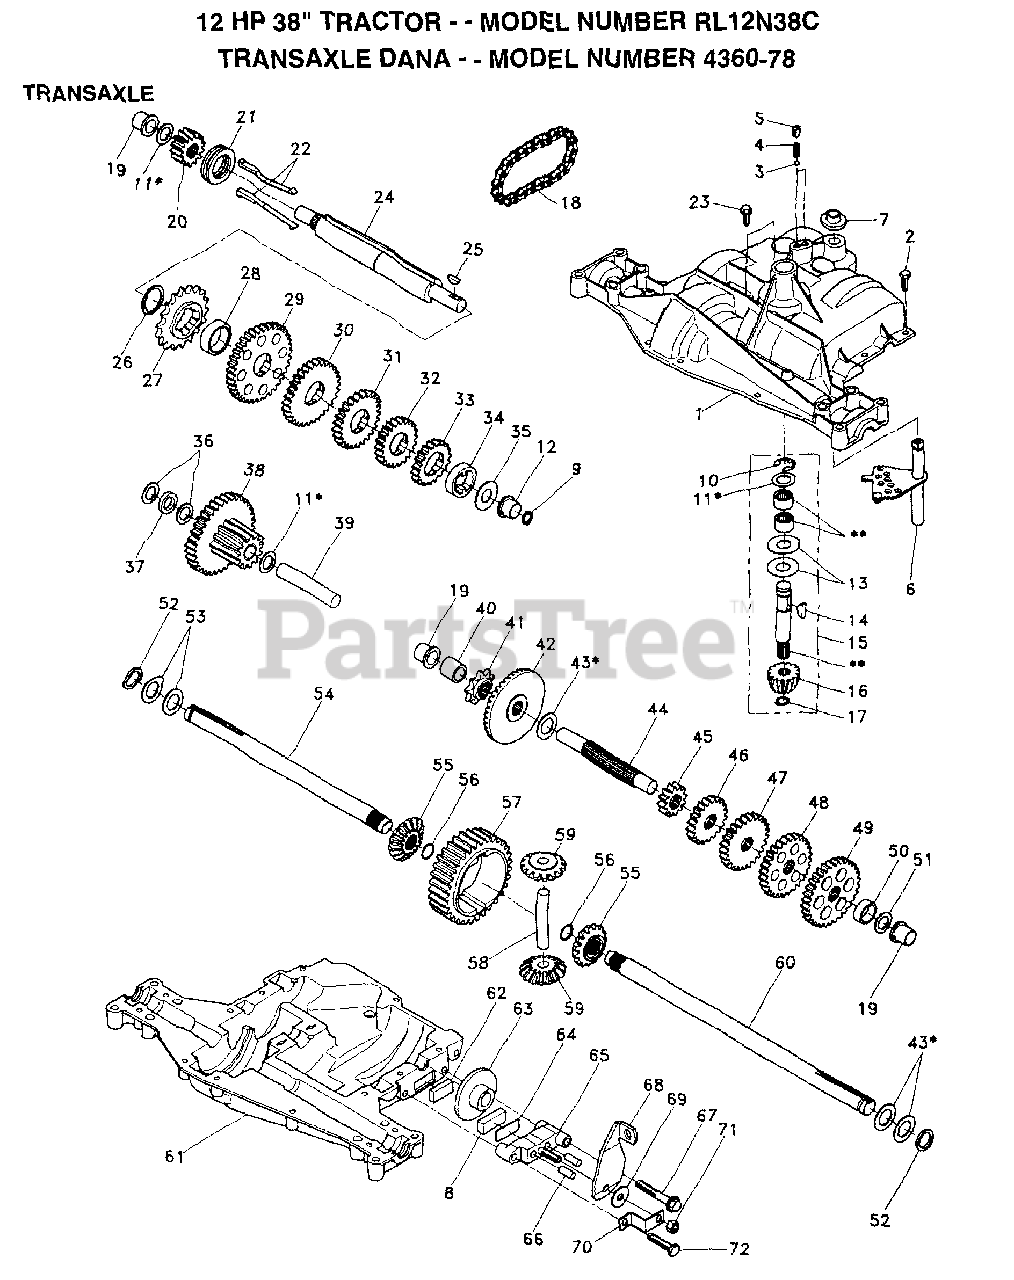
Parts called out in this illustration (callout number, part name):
1	HOUSING UPPER TRN
4	"SPRING, DETENT LT"
5	"SCREW, SET LT"
6	KIT SHIFTER ASM
7	SHIFTER BOOT
8	PUCK T
9	SEAL OIL DANA5416
11	ASM KIT SHIM 4689
13	WASHER T
14	KEY WOODRUFF-DANA
15	AS KIT INPUT SHFT
16	PINION 14T T
17	"RING,RETAINING LT"
18	"CHAIN,24 PTCH LT"
19	BEARING.FLNG.5510
20	GEAR SPUR 14 TTH
21	COLLAR CLUTCH
22	ASM KIT CLTCH KEY
23	SCREW TAP W/SEAL
24	SHAFT INTERM DANA
25	WOODRUFF KEY
26	"RING,RETAINING LT"
27	SPROCKET 18T T
28	SPACER YT
29	GEAR SPUR 37 TTH
31	GEAR 25T LT
32	GEAR SPUR 22 TT
33	SPUR GEAR 19T
34	SPACER
35	"WASHER, PLAIN LT"
36	WASHER 025
37	SPACER
38	ASSM GEAR COMB
39	SHAFT IDLER
40	SPACER T
41	SPROCKET 9T LT
43	ASM KIT SHIM
44	SHAFT T
45	GEAR SPUR 12 TTH
47	"GEAR, SPUR 25T LT"
48	GEAR 28T T
49	"GEAR, SPUR 31T LT"
51	WASHER 060
52	NEOPRENE WASHER
53	WASHER 031
55	GEAR 15T T
56	"RING,RETAINING LT"
58	SHAFT T
59	GEAR 1ST T
61	HOUSING LOWER TNS
62	PUCK T
63	BRAKE DISC. T
64	SPACER LT
66	PIN T
69	WASHER LT
71	NUT.LOCK.5/16-24
72	"SCREW, TAPPING LT"
